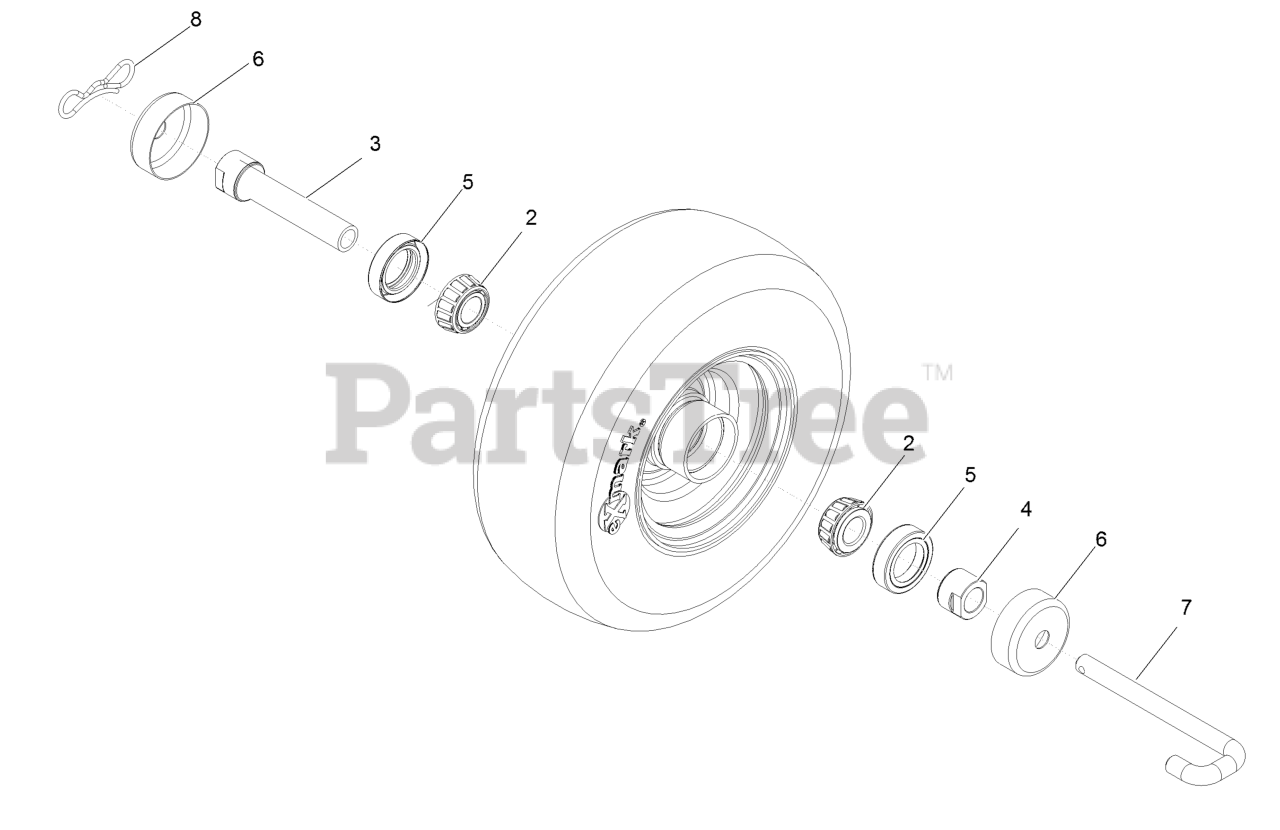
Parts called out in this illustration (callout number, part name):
2	BEARING-CONE, TAPERED ROLLER
3	CASTER AXLE ASM
4	SPACER-NUT
5	SEAL-CASTER
6	GUARD-SEAL
7	PIN, CASTER
8	PIN-COTTER, LOCKING
